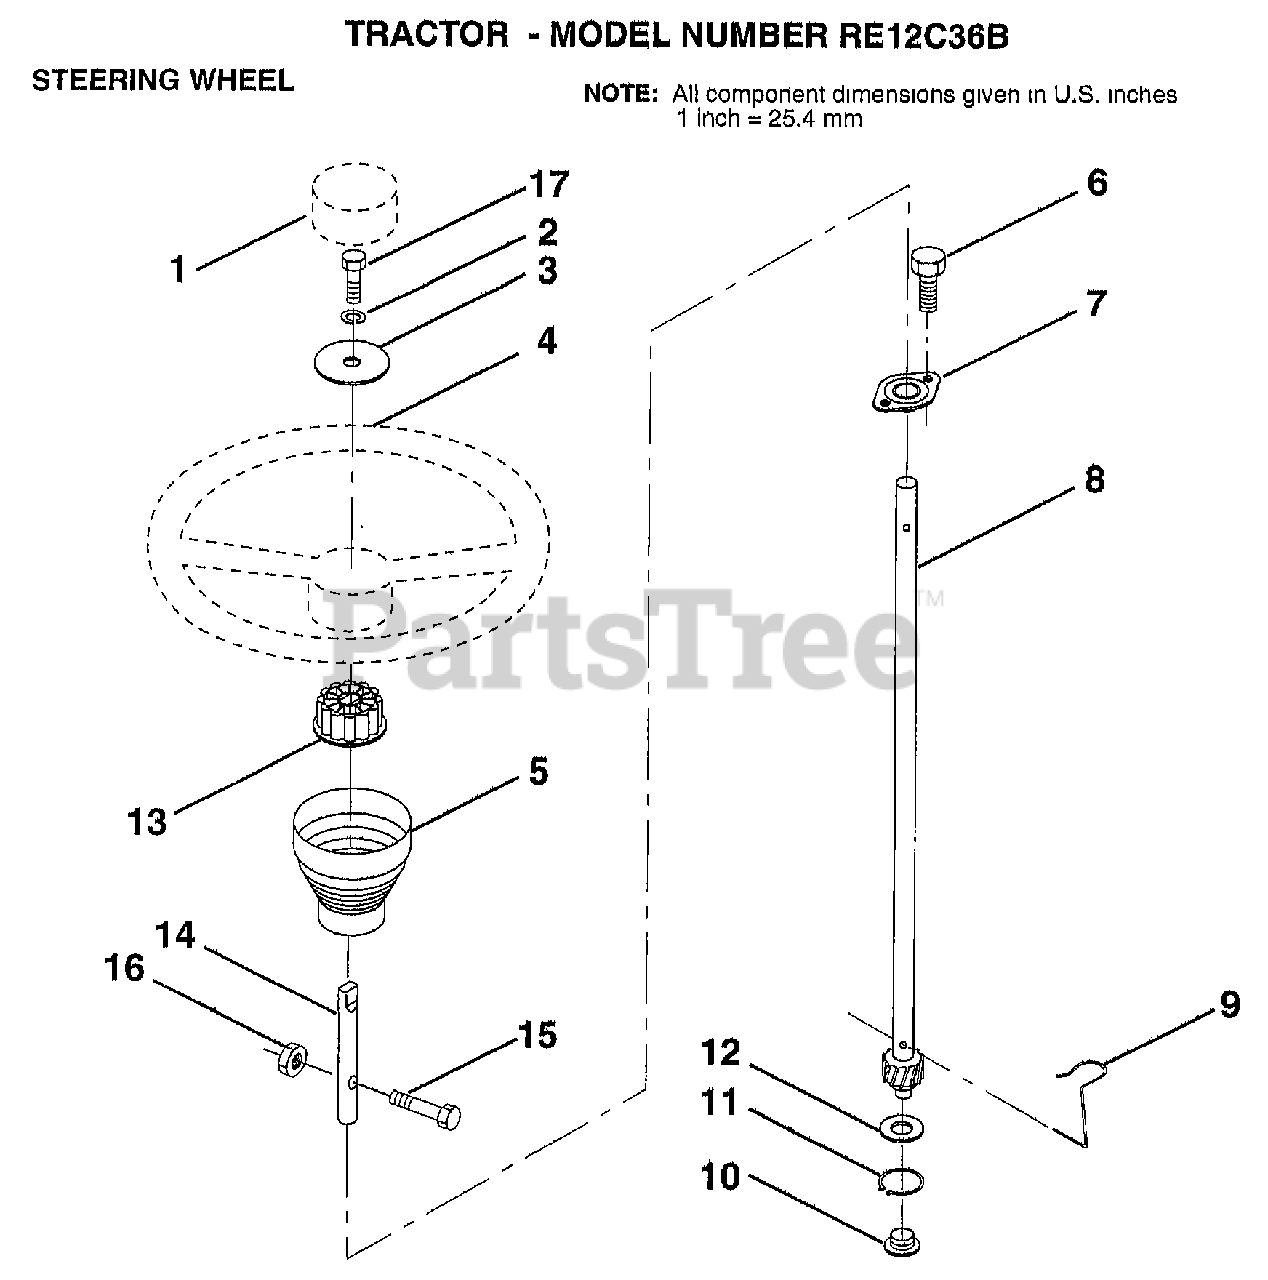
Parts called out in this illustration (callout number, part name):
1	ST WHL INSERT CAP
2	LOCKWASHER
3	WASHER T
5	SLEEVE STEERING
6	"SCREW-TT,10-32 FL"
7	BUSHING.STR.623
8	SHAFT.STEERING.LR
9	STEERING CLIP
10	BUSHING STEER LWR
11	RING
12	WASHER LT
13	ADAPTER LT
14	EXT SHAFT STEERIN
15	BOLT
16	NUT
17	BOLT
